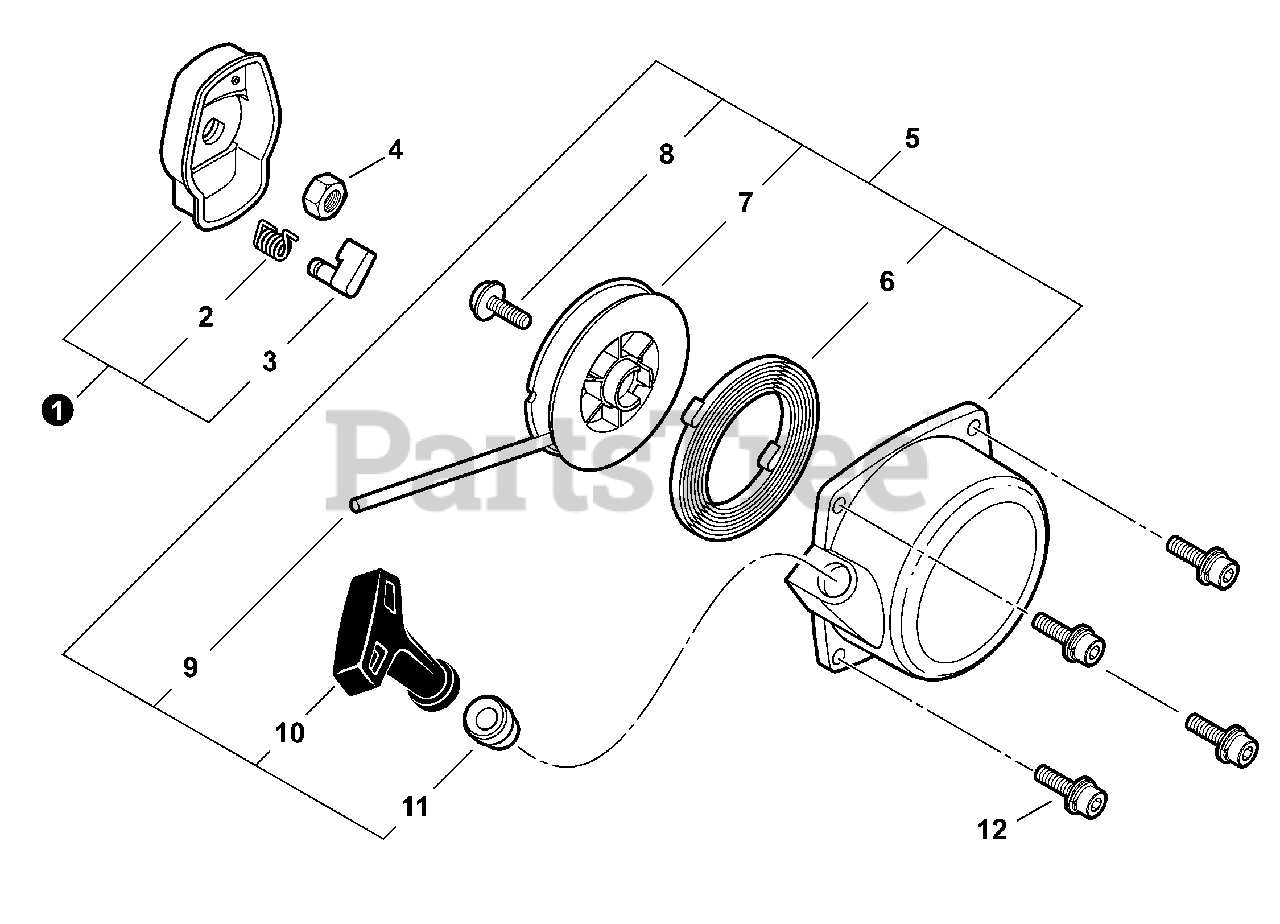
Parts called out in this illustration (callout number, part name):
1	PAWL ASSY, STARTER
2	SPRING, RETURN
3	PAWL, STARTER - BLACK
5	STARTER ASSY, RECOIL
6	SPRING, RECOIL
7	REEL, ROPE
8	SCREW
9	ROPE, STARTER 3.0×1000
10	GRIP, STARTER
11	GUIDE, ROPE
12	BOLT 4×16
